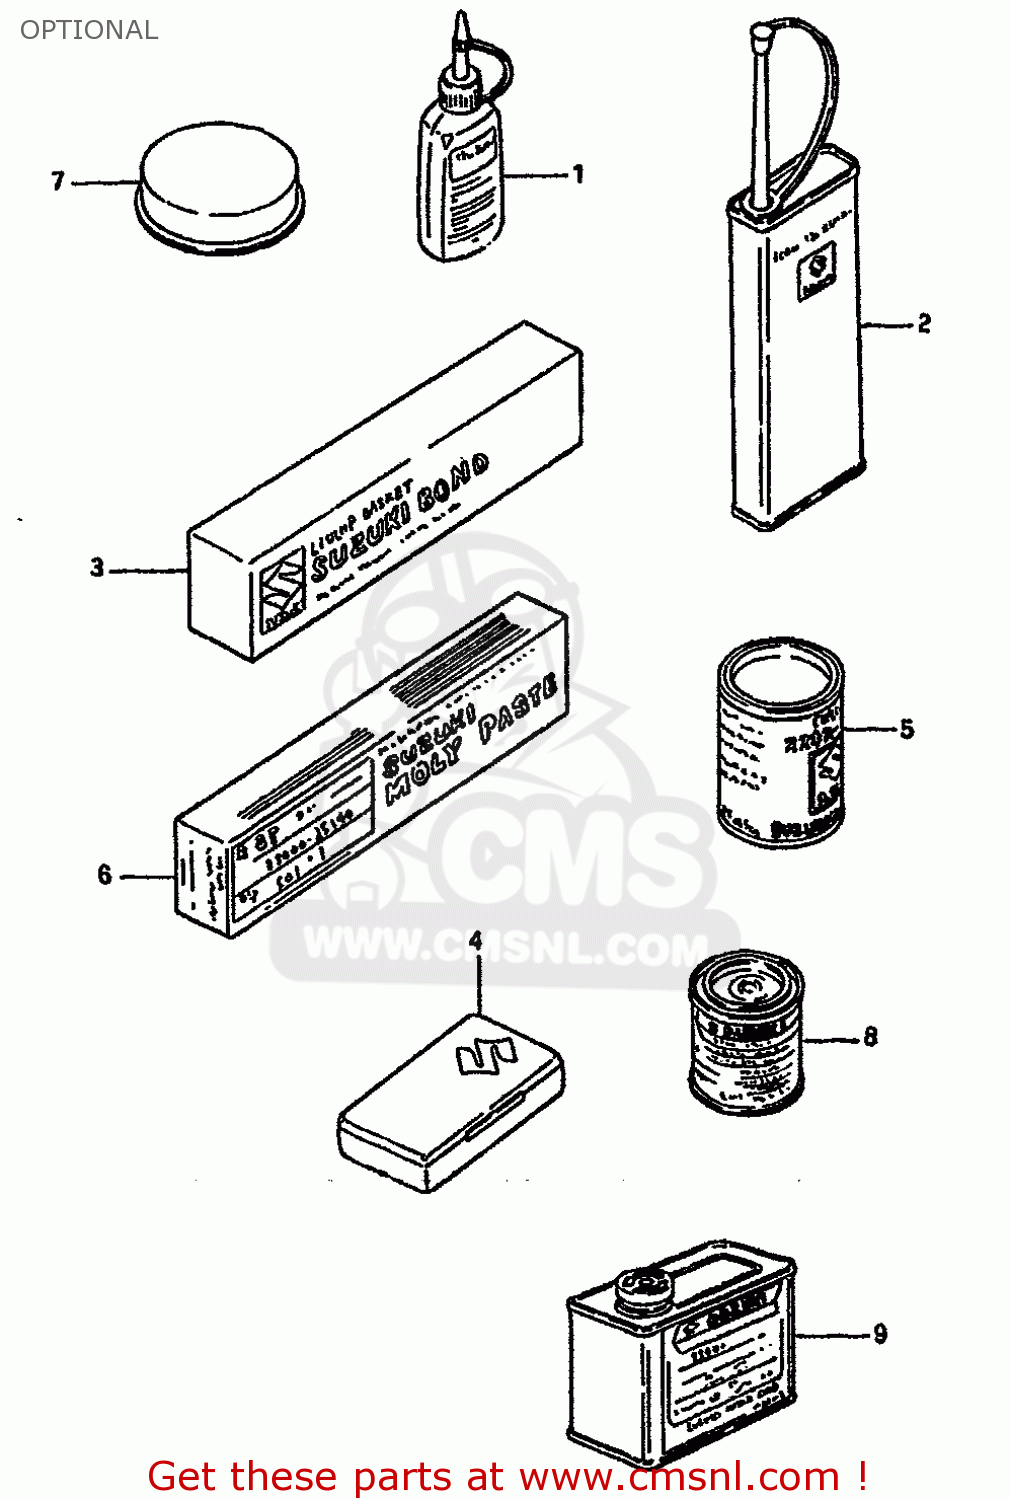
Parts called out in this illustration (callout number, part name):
1	THREAD LOCK NO.1342
2	THREAD LOCK NO.1401 CLEAR 200G
3	LIQUID GSKT NO.1207B 100G BLK
4	TUBE REPARING TOOL
5	GREASE(C)EP2 LITHIUM 150G
6	SUZUKI MOLY PASTE
7	GREASE,PBC FOR BRK PAD 20G
8	PAINT (SPECIAL WHITE)
9	PAINT (SPECIAL WHITE)
